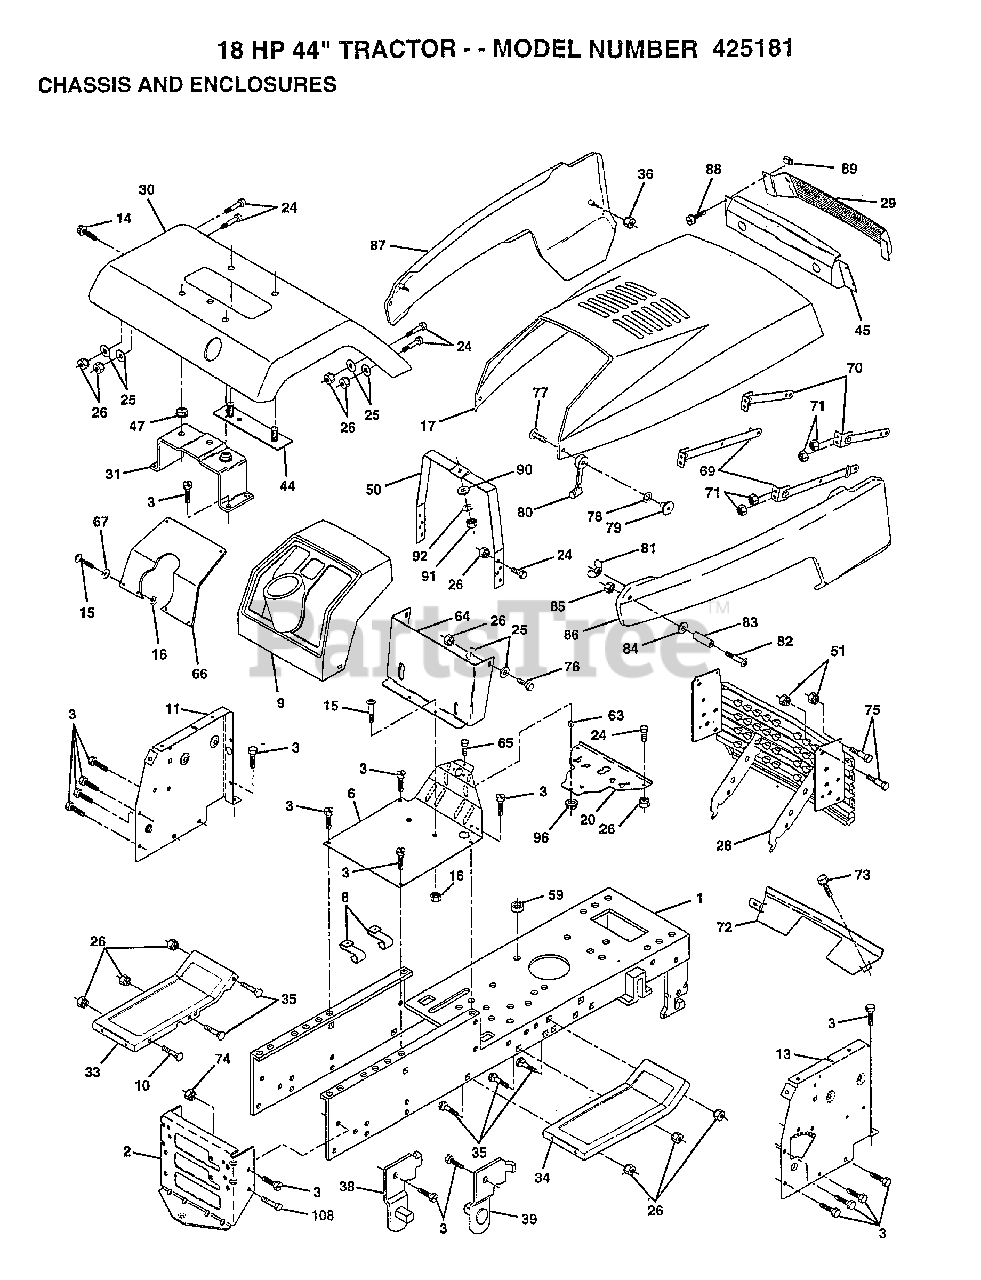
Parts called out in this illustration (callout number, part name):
2	DRAW BAR
3	SCREW
8	"CLIP,INSULATOR"
9	DASHBOARD BLACK
11	PANEL.DASH.LH
13	PANEL.DASH.RH
14	SCREW LT
15	SCREW
20	PLATE.SUPT.BATTER
24	BOLT
25	WASHER
26	NUT
29	LENS LT
30	FENDER.PNT.
31	BRKT.ASM.FENDER
35	BOLT
36	PAL NUT LT
38	BRACKET ASM LH
39	BRACKET ASM RH
44	STRAP ASM FENDER
47	NUT-PUSH YT
50	SUPPORT ASS'Y
51	NUT
63	SPACER
64	LOWER DASH
65	BOLT
66	PLATE SLKSCR YP
67	WASHER
71	NUT HXKEP 1/4X20
72	STRAP.GRILLE.PNT.
73	SCREW CRT
76	BOLT
77	SCREW
78	LOCKWASHER
79	WELDNUT
80	HOOD LATCH T
82	SCREW
83	SPACER LT
84	WASHER
86	PANEL SIDE RH
89	"""J"" FASTENER LT"
90	WASHER PM
92	LOCKWASHER
96	NUT
